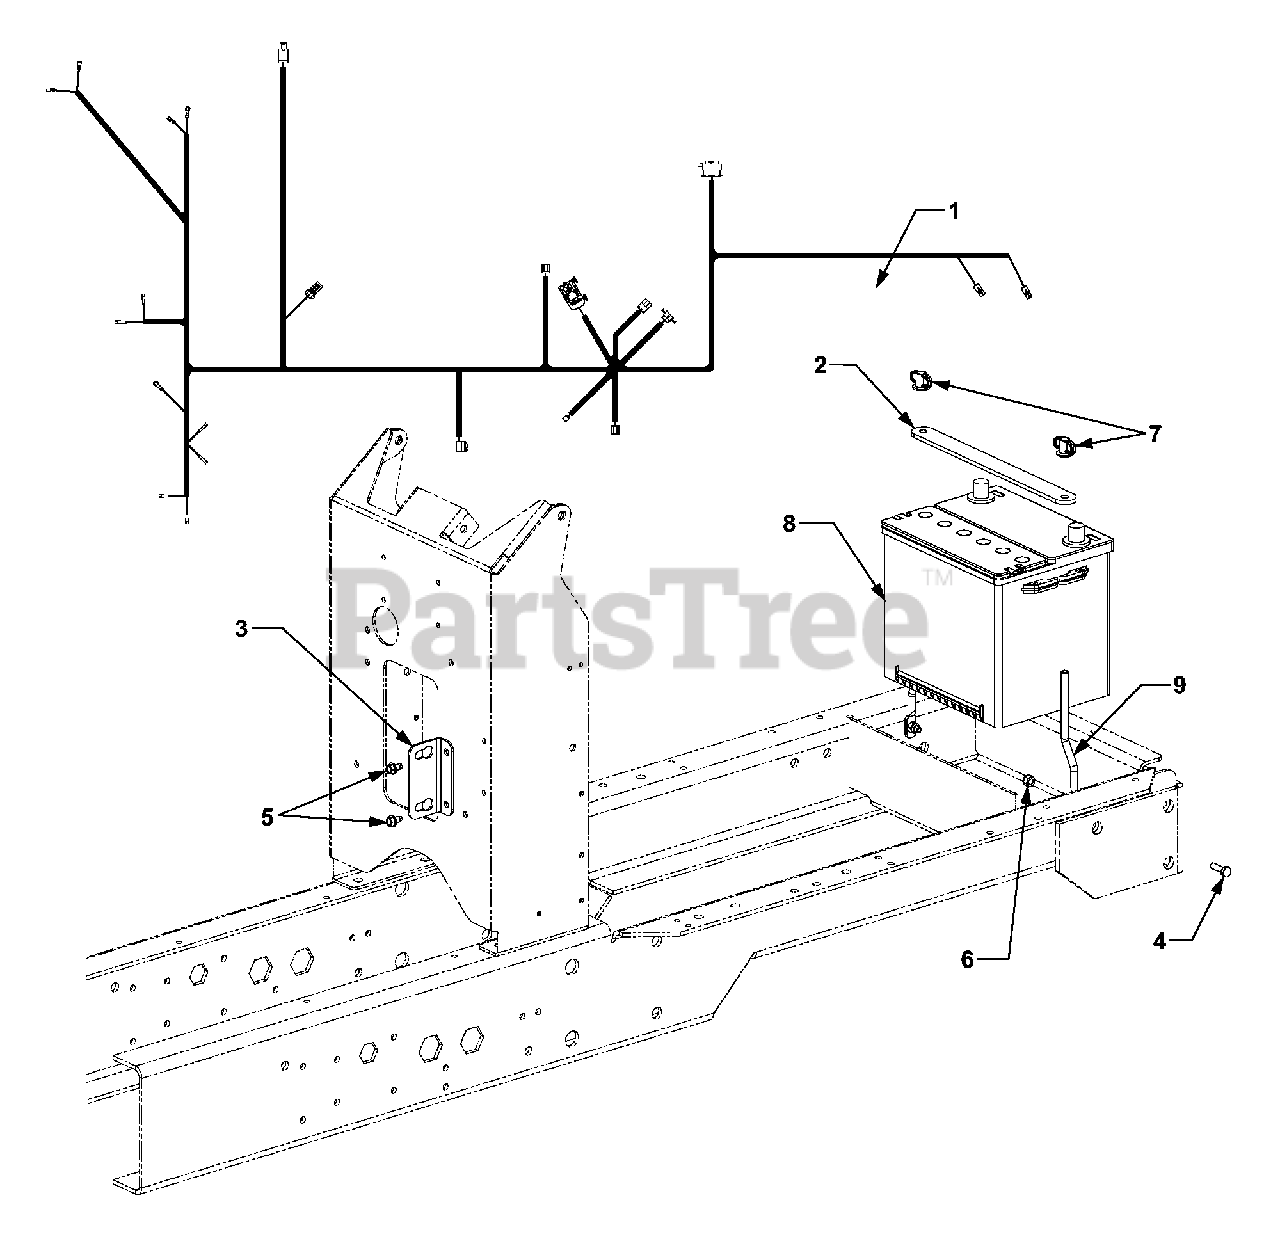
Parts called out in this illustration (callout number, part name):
1	Harness, Main Wire
2	Strap, Battery Holddown
5	Screw, Hex Wash Hd. Tapp 1/4-20 x .5
6	Nut, Hex Nylon Insert Lock, 1/4-20
7	Nut, Wing w/Bell Washer, 5/16-18
8	Battery, 500 cca Dry
9	Rod, Battery Holddown
